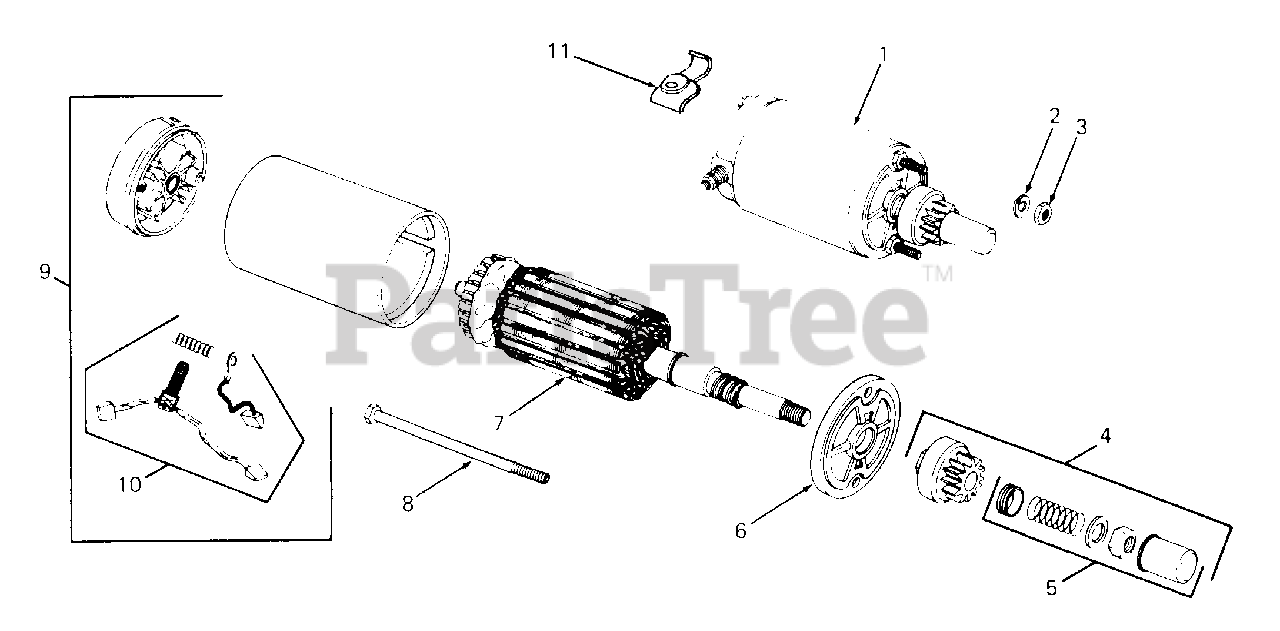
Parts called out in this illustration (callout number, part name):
1	Starter Assembly
2	Washer, Lock, 1/4
3	Nut, Hex, 1/4-20
4	Kit, Drive
5	Kit, Drive Parts
6	Cap, Drive End
9	Cap, Commutator End
10	Kit, Brush
11	Bracket, Mounting
